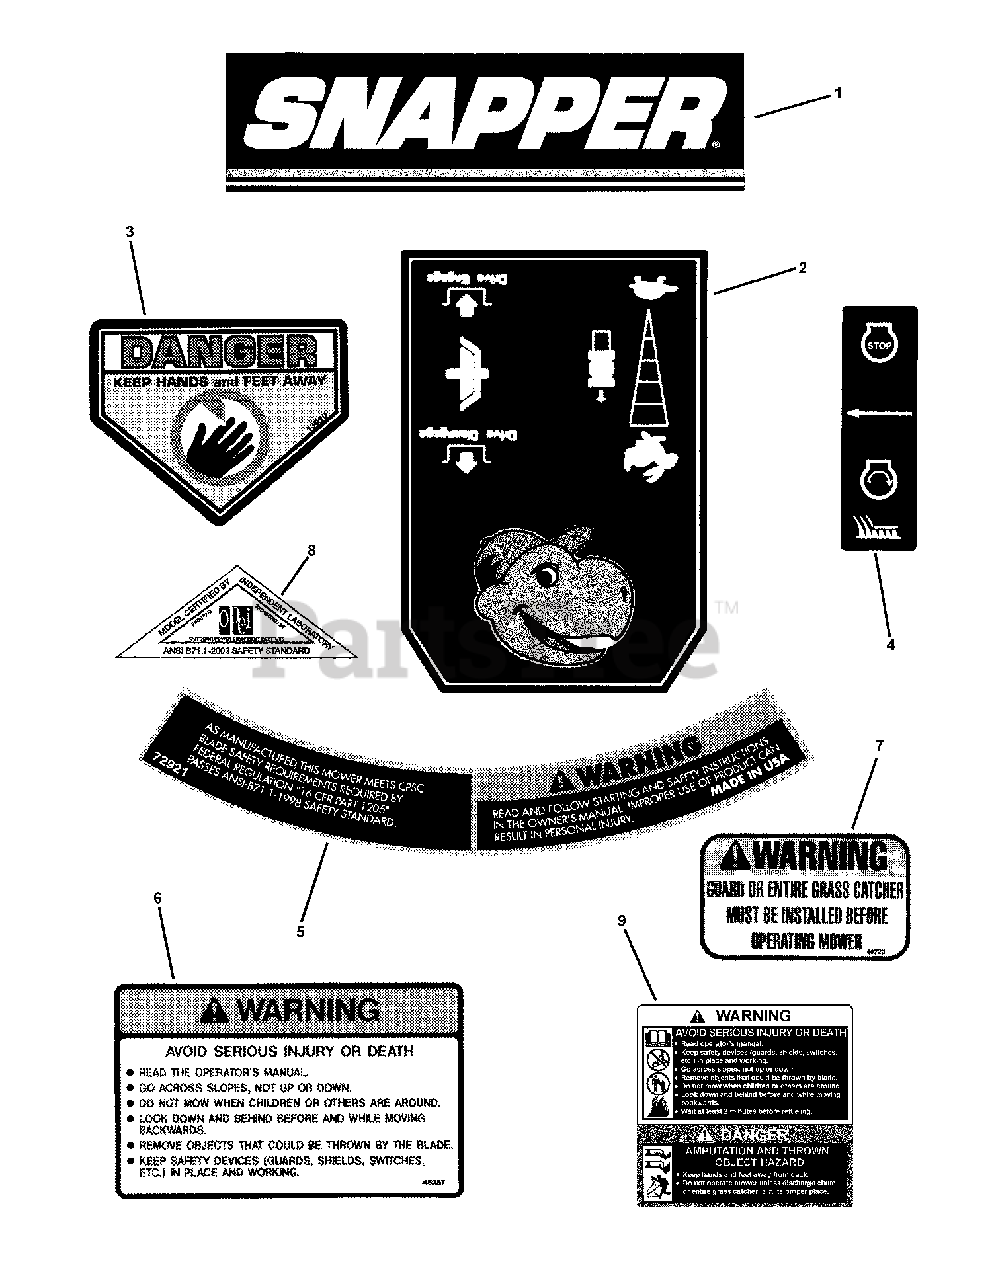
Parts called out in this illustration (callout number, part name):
1	DECAL, SNAPPER Logo
2	DECAL, Control Head, Variable Speed
3	DECAL, Danger, Cut Finger
4	DECAL, OPC Bail International Symbol
5	DECAL, Warning (Deck)
6	DECAL, Warning 1997
7	DECAL, Chute/Deflector
8	DECAL, OPEI Walk/Ride
9	DECAL, Warning/Danger WBM
